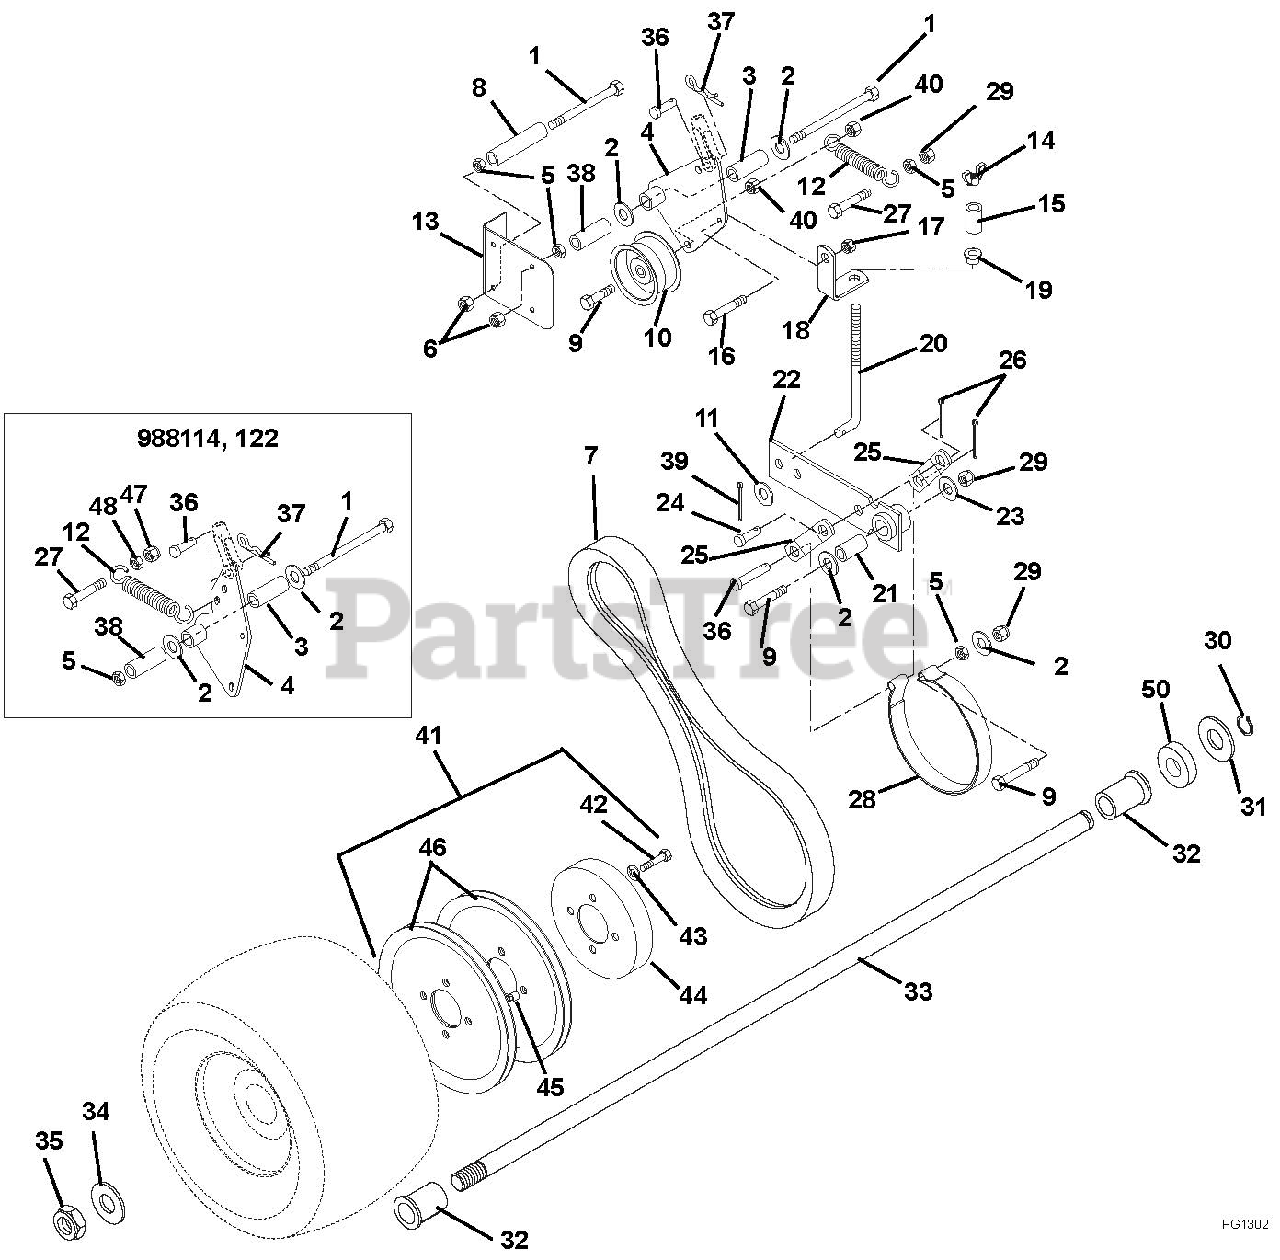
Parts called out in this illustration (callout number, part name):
1	Bolt-Hex .38-16 x 4.50 Grade 5
2	Washer-Flat-Steel .406 x .812 x .065
3	Bushing, Steel .385 x .610 x 1.80
4	Weldment- Wheel Clutch Arm
5	Nut-Hex .38-16
6	Nut-Locking-Flange .375-16
7	Belt, Traction Drive
8	Bushing, Spacer, 3.25 x .38 I.D. x .63 O.D.
9	Bolt-Hex .38-16 x 2.00 Grade 5
10	Sheave 3.25 x 1.25
11	Washer-Flat-Steel .344 x .688 x .065
12	Spring-Tension .105 x 1.00 x 5.00
13	Kit-Belt Cover with Decals
14	Nut-Nylock Wing .31-18
16	Bolt-Hex .25-20 x .75 Grade 5
17	Nut-Locking-Nylon .25-20
18	Bracket, Brake Link
19	Bushing-Flange .32 x .62 x .312 Nylon
20	Rod, Brake
21	Bushing Sleeve .39 x .622 x .95 Steel
22	Weldment, Brake Arm
23	Washer-Flat-Steel .406 x 1.00 x .188
24	Pin-Clevis .38 x .75
25	Link, Brake Arm
26	Pin-Cotter .12 x .75
27	Bolt-Hex .38-16 x 1.50 Grade 5
27	Bolt-Hex .31-18 x 2.00 Grade 5
28	Assembly, Pro Brake Band
29	Nut-Locking-Nylon .38-16
30	Ring-Retaining-External .906 x .078
31	Washer-Flat-Steel 1.01 x 1.50 x .062
32	Bushing-Flange 1.01 x 1.38 x 1.4 x 1.65
33	Shaft, Axle
34	Washer-Flat-Steel .812 x 1.50 x .135
35	Nut-Locking-Jam-Nylon .75-10
36	Pin-Clevis .38 x 1.25
37	Pin-Hair Internal .08 x .18 x 1.18
38	Bushing, Spacer
39	Pin-Cotter .09 x .75
40	Nut-Locking-Jam-Center .38-16
41	Assembly, Pulley and Drum
41	Assembly, Pulley and Drum 11" OD
42	Bolt-Hex .31-18 x 1.50 Grade 5
43	Washer-Locking .31 x .078 Regular
44	Drum, Brake
45	Bushing, Sleeve .385 x .625 x .475 Steel
46	Sheave 8"
46	Pulley, Gear Drive Wheel 11"OD
47	Nut-Locking-Center .31-18
48	Nut-Hex .31-18
49	Kit, Belt Cover with Decals
50	Bushing, Sleave 1.04 x 1.75 x 5.00 ST
